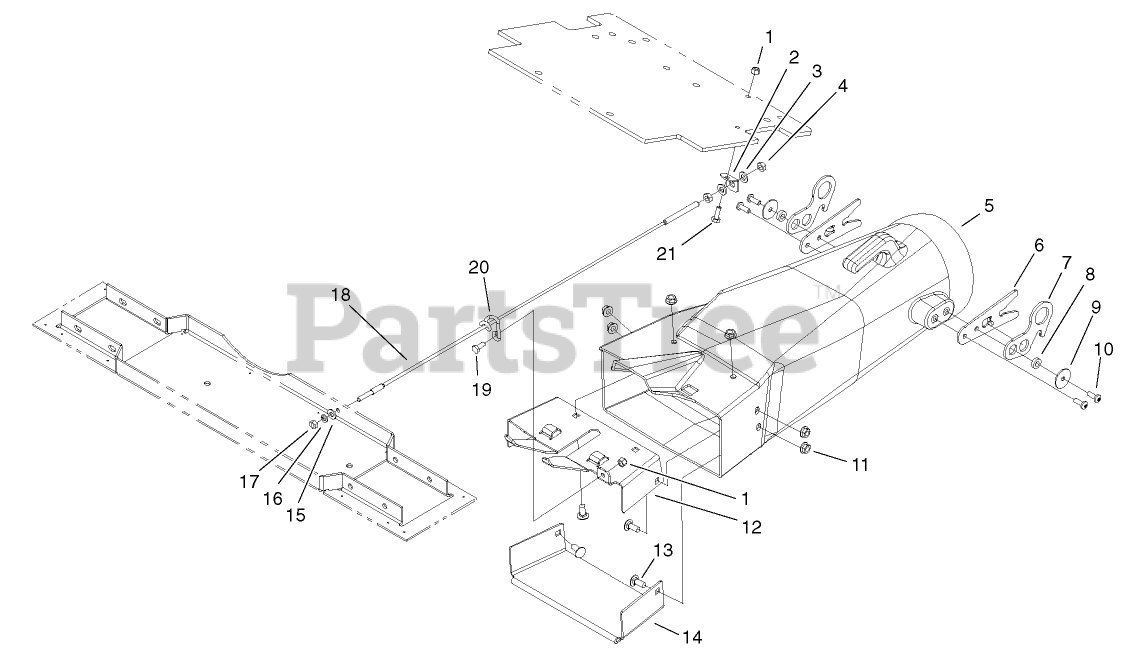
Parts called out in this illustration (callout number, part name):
1	NUT-LOCK, NI
2	BRACKET-SPRING
3	WASHER-PLAIN
4	NUT-JAM
5	PLENUM
6	PLATE-GUIDE
7	PLATE-LATCH
8	SPACER
9	WASHER-FLAT
10	SCREW-TORX
11	NUT-HF
12	PLATE-PLENUM, TOP
13	SCREW-CARR
14	PLATE-PLENUM, BOTTOM
15	WASHER-FLAT
16	WASHER-LOCK
17	NUT-HEX
18	CABLE-TENSION
19	SCREW-HH
20	GUIDE-CABLE
21	SCREW-HH
